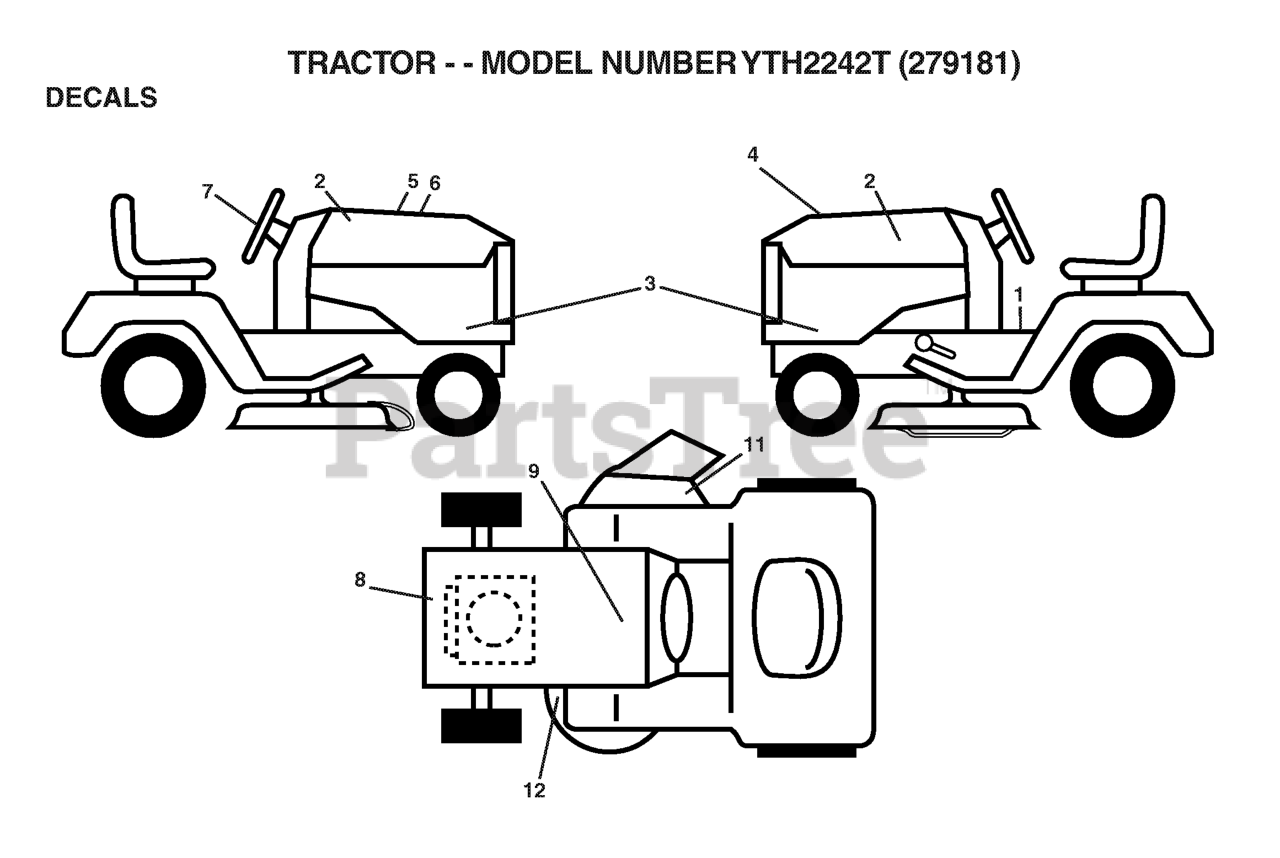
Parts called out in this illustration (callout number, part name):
1	DECAL.FENDER.OPER.TEX.
2	DECAL.HOOD.LOGO.PLAQUE
3	DECAL.PANEL.SD.YTH2242
4	DECAL.HOOD.TOP.INSERT.
5	DECAL HOOD CUST. RESP.
6	DECAL, REPLACEMENT
7	DECAL.WHEEL.STRG.LGN.H
8	DECAL.B&S.22HP#275796
9	DECAL BTRY SYMBOLS
11	DECAL.WARN.KEEP.HAND.AWAY
12	DECAL V BELT SCHEMATIC
